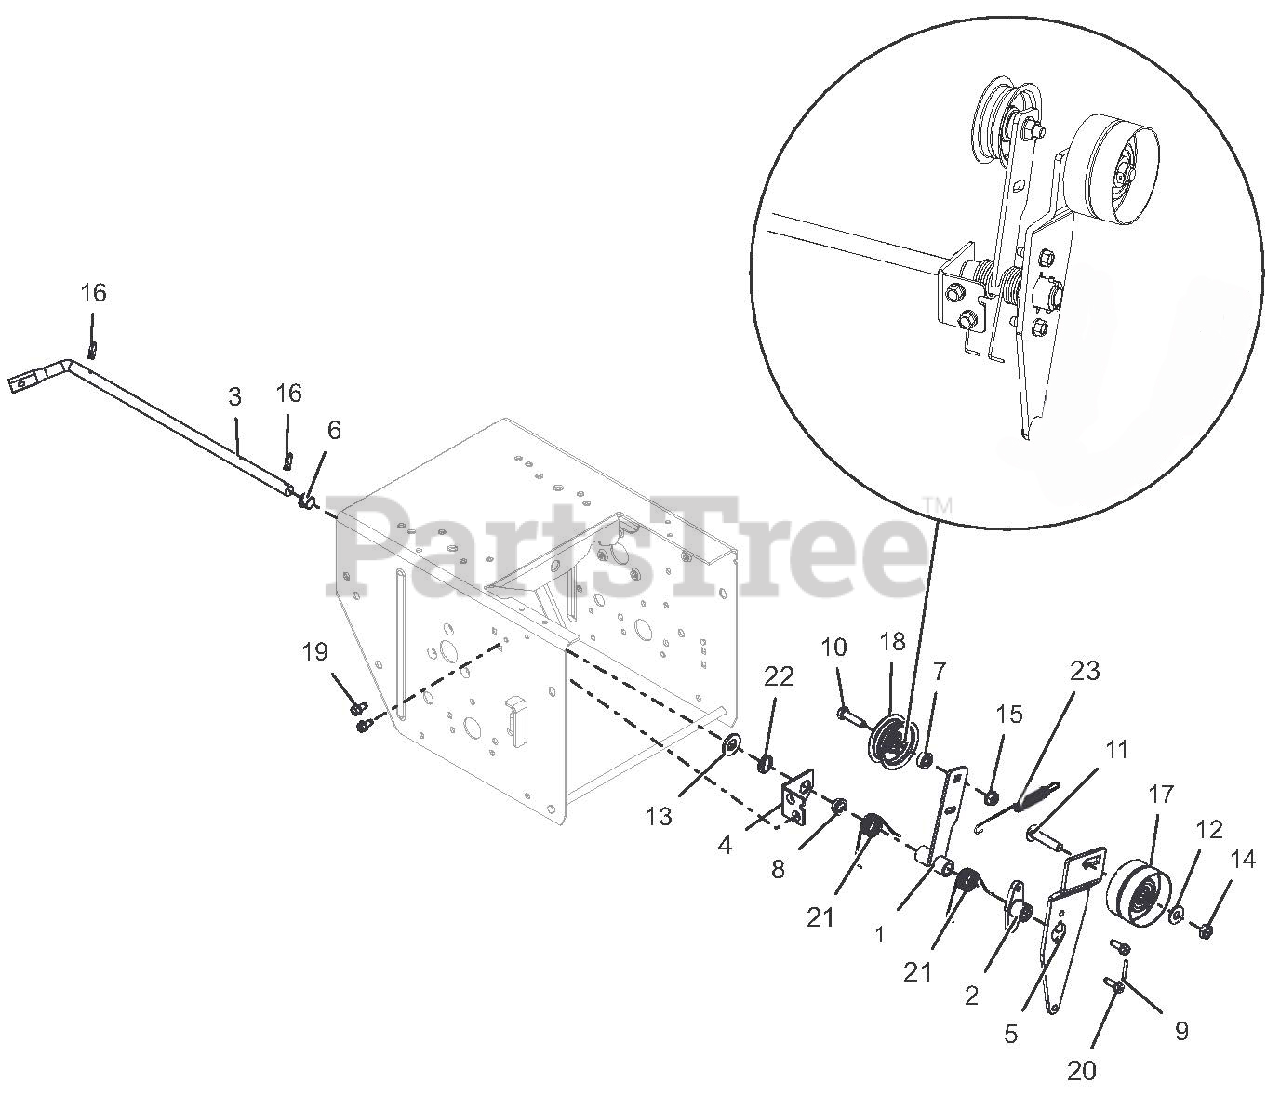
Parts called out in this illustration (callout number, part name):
1	ARM, IDLER-TRACTION
2	HUB, BRAKE ARM
3	ARM, ATTACHMENT
4	BRACKET, SUPPORT
5	ARM, IDLER-ATTACHMENT
6	BUSHING, POLYLINER-.50 SPLIT
7	SPCR, BRG .315X.500X.358X.281
8	BSHG,FLANGE .500X.625X.270X.75
9	PIN-ROLL .125X1.00
10	@BLT-HEX .31-18X1.25 GR5 YWZC
11	@BLT-RHDSSQNK .38-16X1.75 G5YZ
12	@WSHR-FL-STL.38X.875X.083 YWZC
13	@WSHR-FL-STL.531X1.06X.095YWZC
14	@NUT-LK-CTR-JAM .375-16 YWZC
15	@NUT-LK-TOP-FLG .31-18 YWZC
16	CLIP, SPRING
17	IDLER, FLAT-2.75 OD X .375 ID
18	IDLER, FLAT - 2.00"
19	SCR-TAP .25-20X.50 HWH TR YWZ
20	SCR-TAP-PM .25-20X.75 TR YWZ
21	SG-TORS .067X.88
22	WAVE SPRING .600X.875X.25FH
23	SG-TENS .06X.482X5.35
